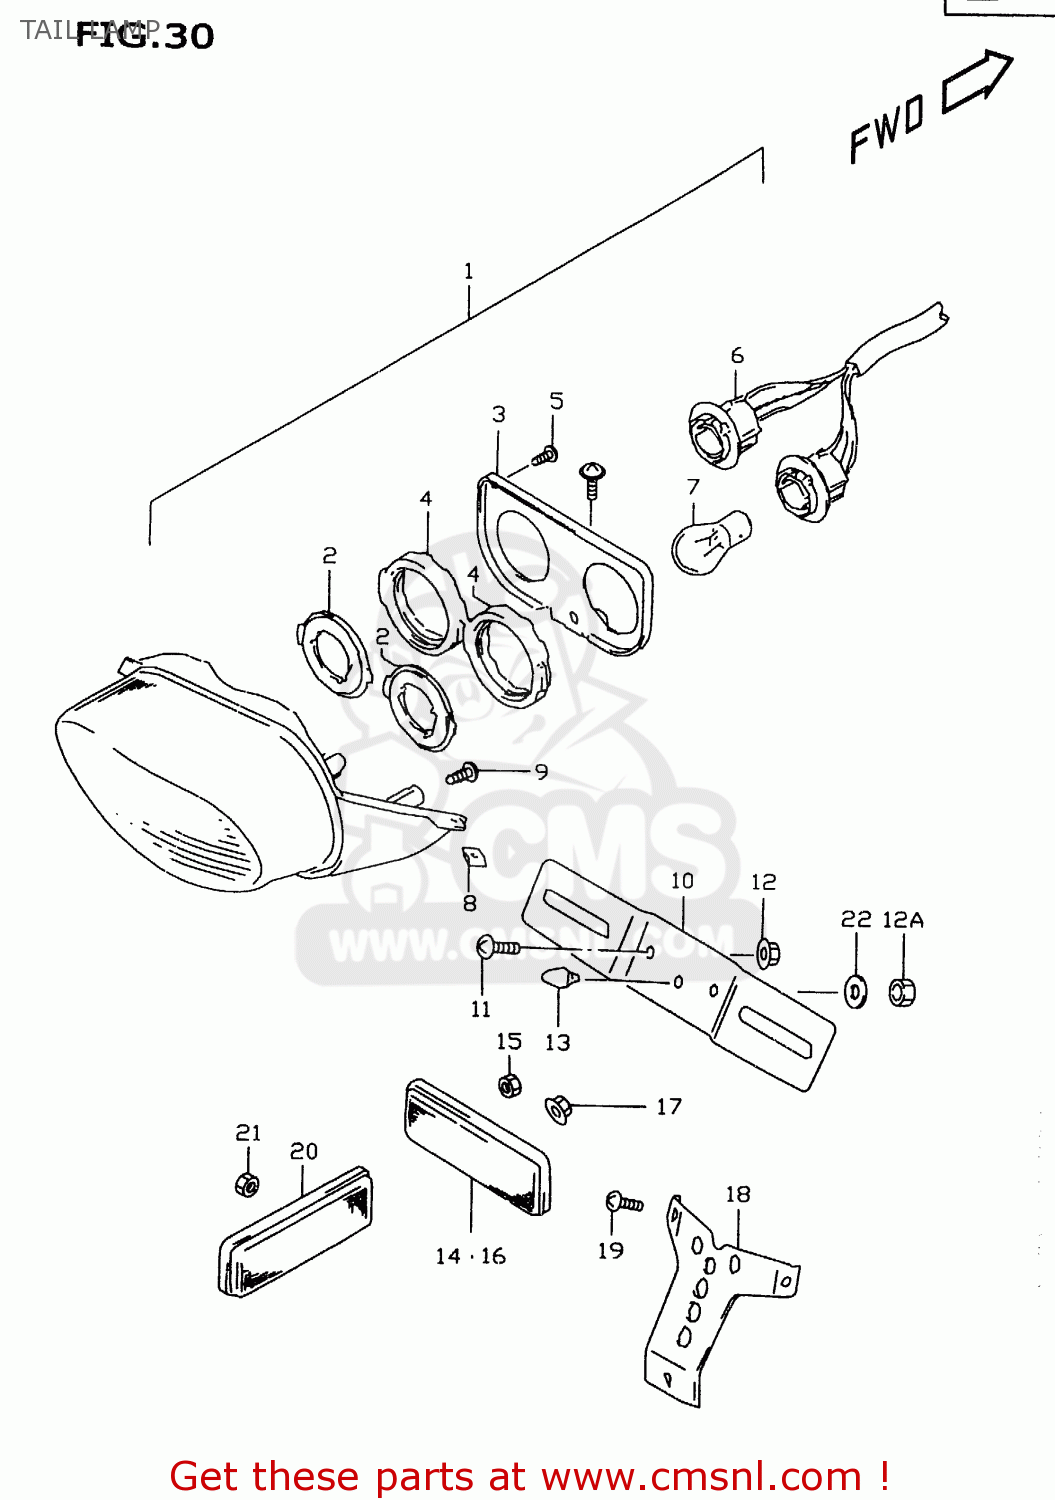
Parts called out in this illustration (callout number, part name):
1	LAMP ASSY,RR COMBINATION
2	PLATE NO.1
3	PLATE NO.2
4	CUSHION
5	SCREW
6	SOCKET & CORD
7	BULB(12V21/5W)
8	NUT
9	SCREW
10	PLATE,RR LICENSE
11	SCREW 6X12
12	NUT
12A	NUT 6MM
13	CUSHION
14	REFLECTOR ASSY,RR
15	NUT
16	REFLECTOR ASSY,RR
17	NUT
18	BRACKET,RR REFLECTOR
19	SCREW(6X12)
20	REFLEX REFLECTOR,FR SIDE
21	NUT
22	WASHER(6.5X20X1.2)
